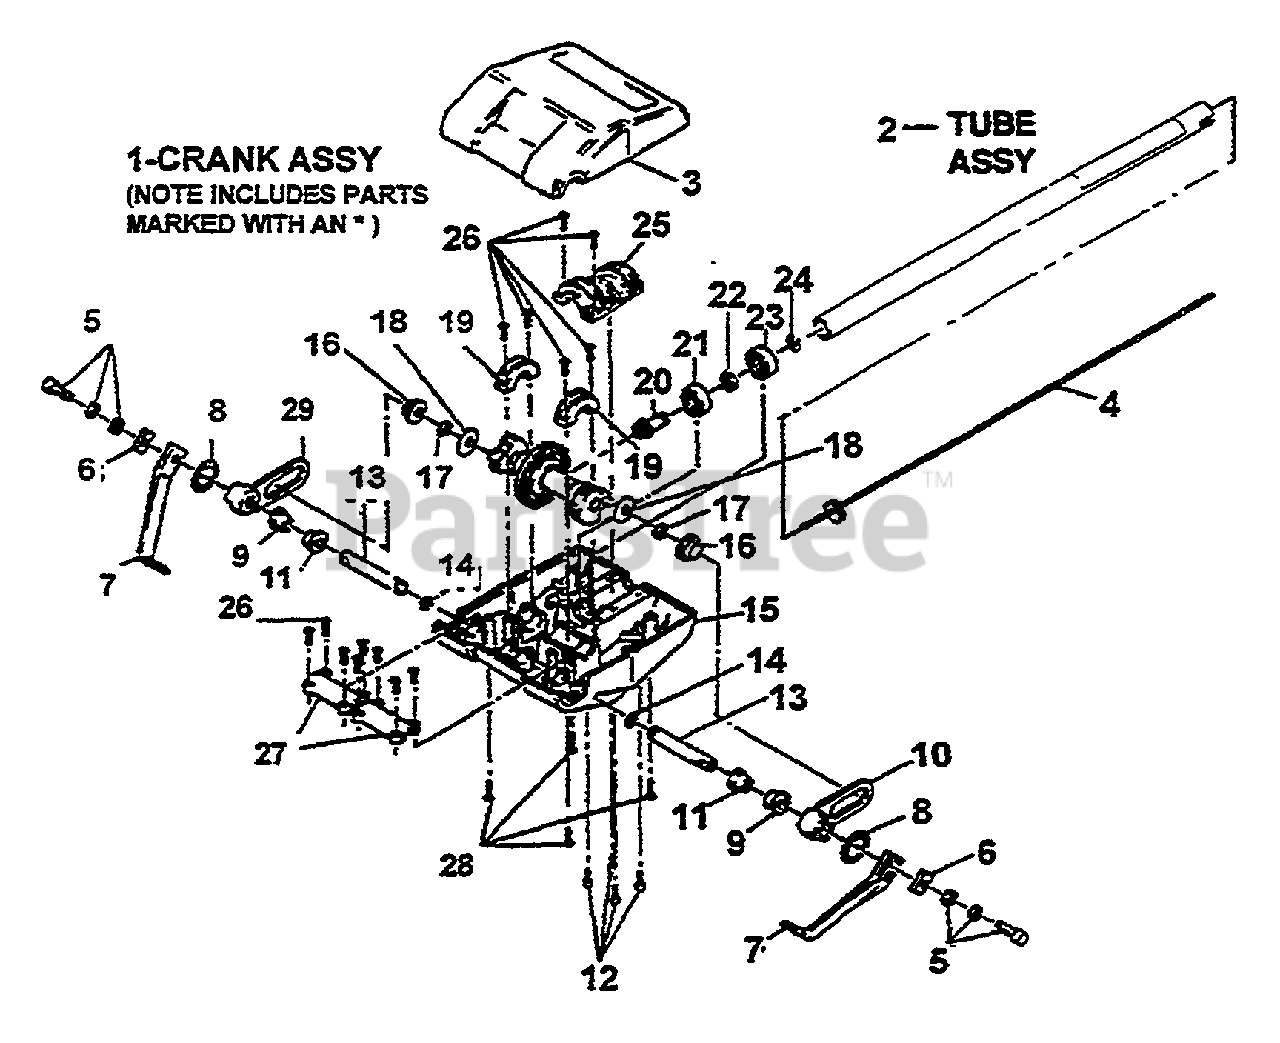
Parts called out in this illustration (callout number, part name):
1	CRANK ASSY
2	TUBE ASSY
3	UPPER COVER
4	FLEX CABLE
5	BOLT, SEMS
6	TINE SUPPORT
8	"O" RING
10	ROCKER ARM L.H.
12	SCREW
13	ROCKER SHAFT
14	WIRE RING
15	LOWER COVER
16	BEARING CAP
17	NEEDLE BEARING
18	WASHER
19	CRANKSHAFT CLAMP
20	PINION GEAR
21	BEARING
24	SNAP RING
25	SHAFT CLAMP
26	SCREW
27	SHAFT CLAMP
29	ROCKER ARM R.H.
